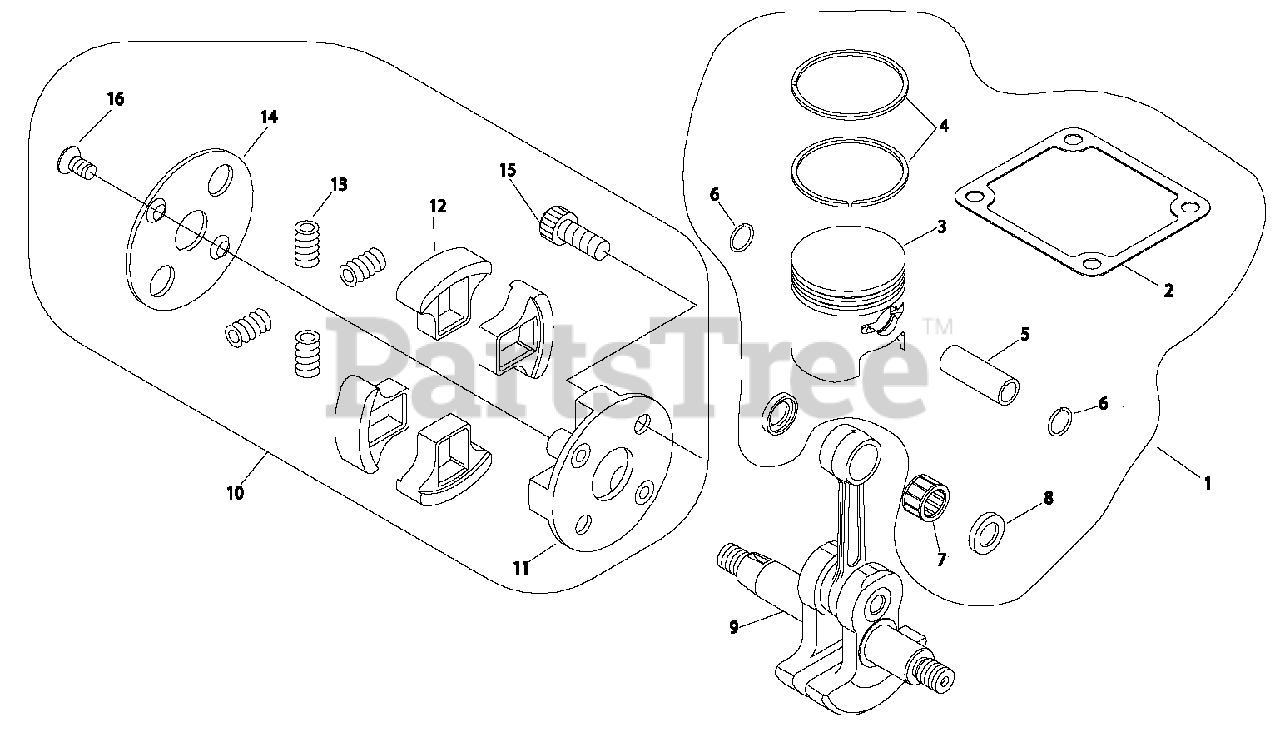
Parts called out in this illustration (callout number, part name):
1	PISTON KIT
2	GASKET, CYLINDER
3	PISTON
4	RING, PISTON
5	PIN, PISTON
6	RING, RETAINING
7	BEARING, NEEDLE - 10
8	SPACER, PISTON
9	CRANKSHAFT ASSY
10	CLUTCH ASSY
11	HUB, CLUTCH
12	SHOE, CLUTCH
13	SPRING, CLUTCH
14	PLATE, CLUTCH
15	BOLT, CLUTCH
16	SCREW
